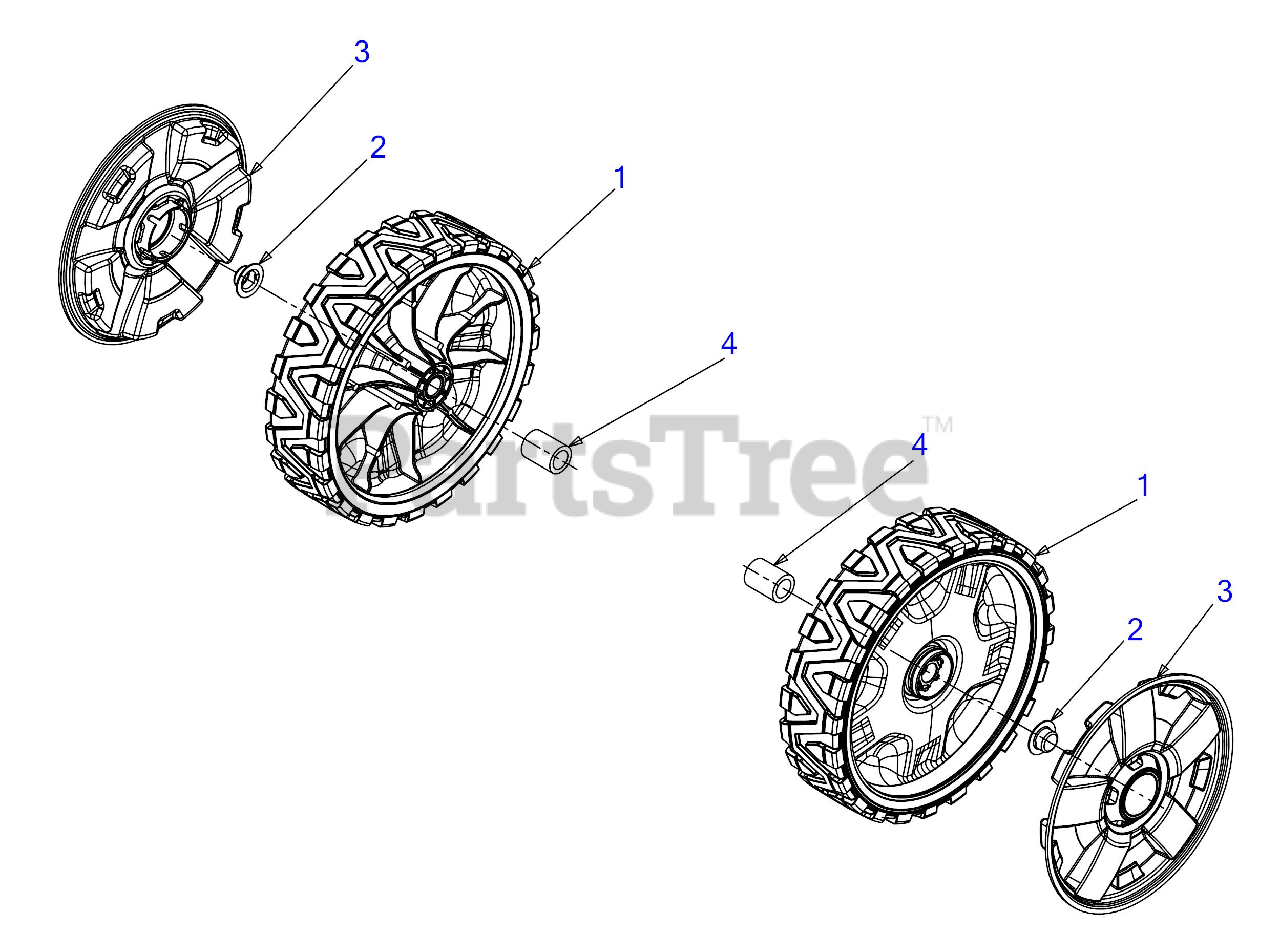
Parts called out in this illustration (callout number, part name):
1	WHEEL ASSEMBLY (8 x 2)
2	PUSH CAP
3	HUBCAP
4	SPACER .525 X .775 X 1.015
